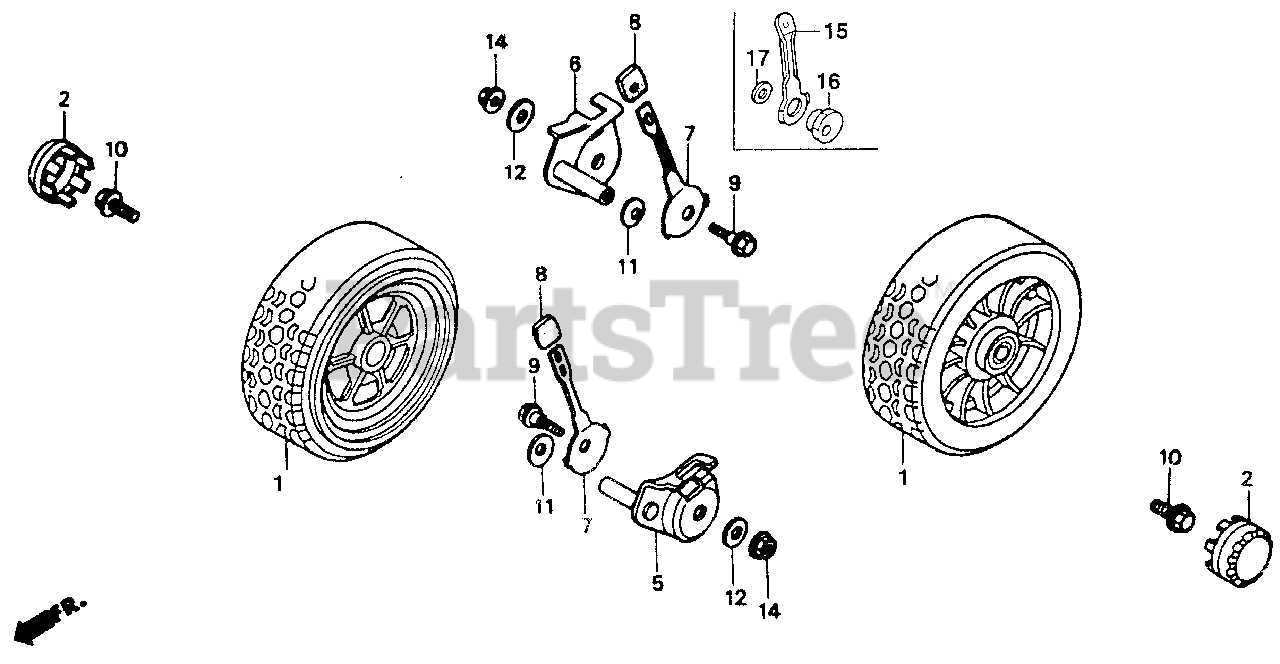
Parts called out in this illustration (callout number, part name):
1	WHEEL (8") *NH31* (MCKINLEY WHITE)
2	CAP, WHEEL
4	TIRE (8 INCH)
5	ADJUSTING KIT, WHEEL
5	ARM A, WHEEL ADJUSTING (NOT AVAILABLE)
6	ARM B, WHEEL ADJUSTING
7	PLATE, FR. ADJUSTER
8	GRIP, ADJUSTER
9	BOLT, ADJUSTING CENTER
10	BOLT, WHEEL
11	WASHER, WHEEL
12	WASHER A, HANDLE HOLDER SETTING
14	NUT, FLANGE (8MM)
15	PLATE, FR. ADJUSTING (PART NEWS #006)
16	ADJUSTING KIT, WHEEL
17	WASHER, HEAD (8MM)
